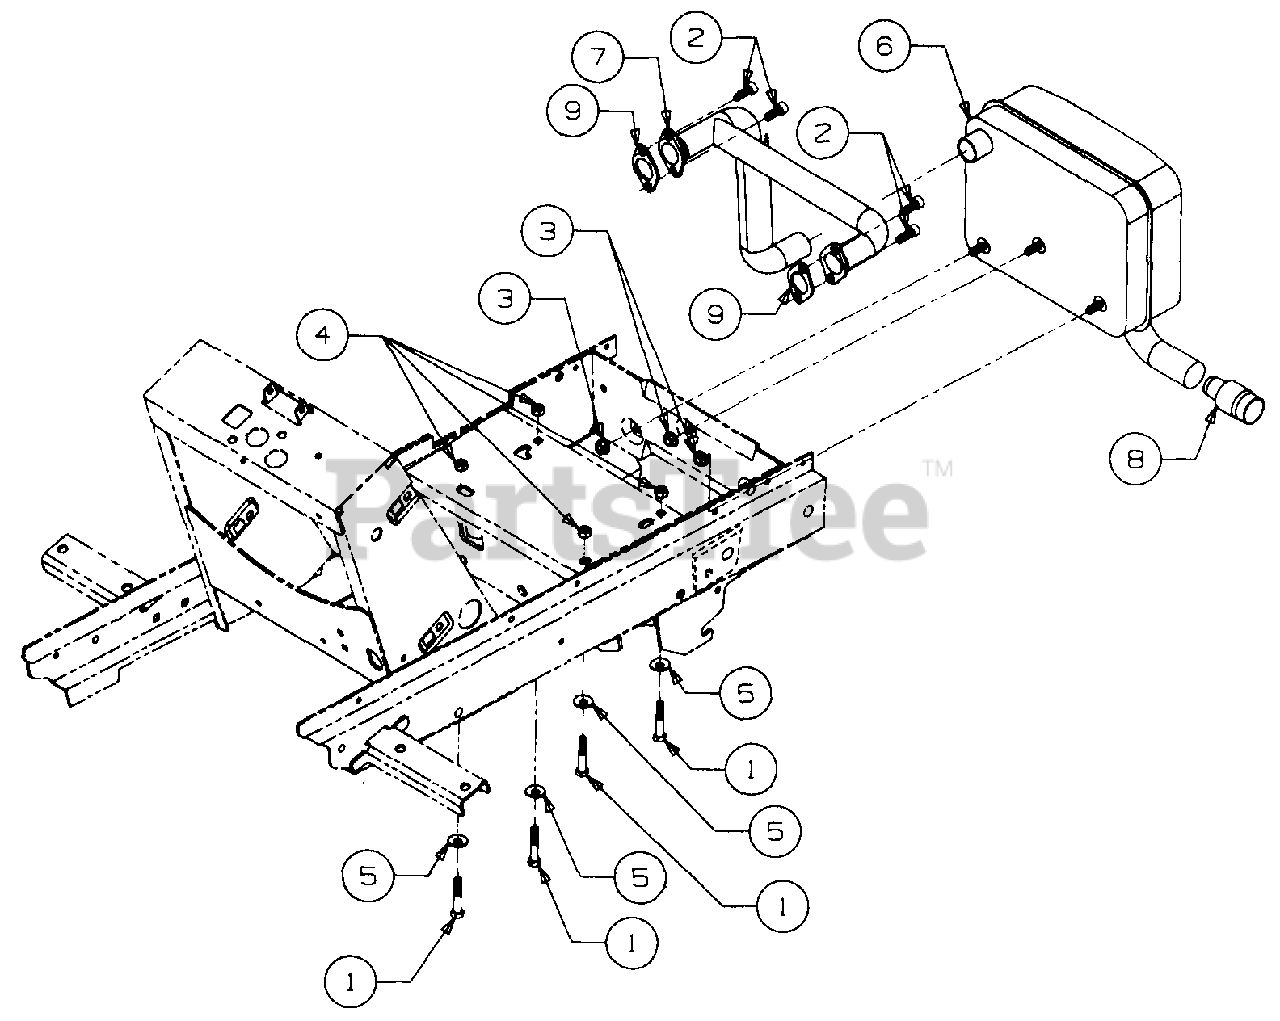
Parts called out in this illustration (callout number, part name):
1	Bolt, Engine Mtg. 5/16-18 x 1.75 Lg GR5
2	Screw, Socket Hd Cap, M8-1.25 x 20mm Lg
3	Nut, Hex Flange Top Lock, 5/16-18
4	Nut, Hex, 5/16-18 GR5
5	Washer, Bell, .345 x .88 x .060 Thk
6	Muffler Assembly
7	Tube, Exhaust
8	Arrestor, Spark
9	Gasket, Exhaust
